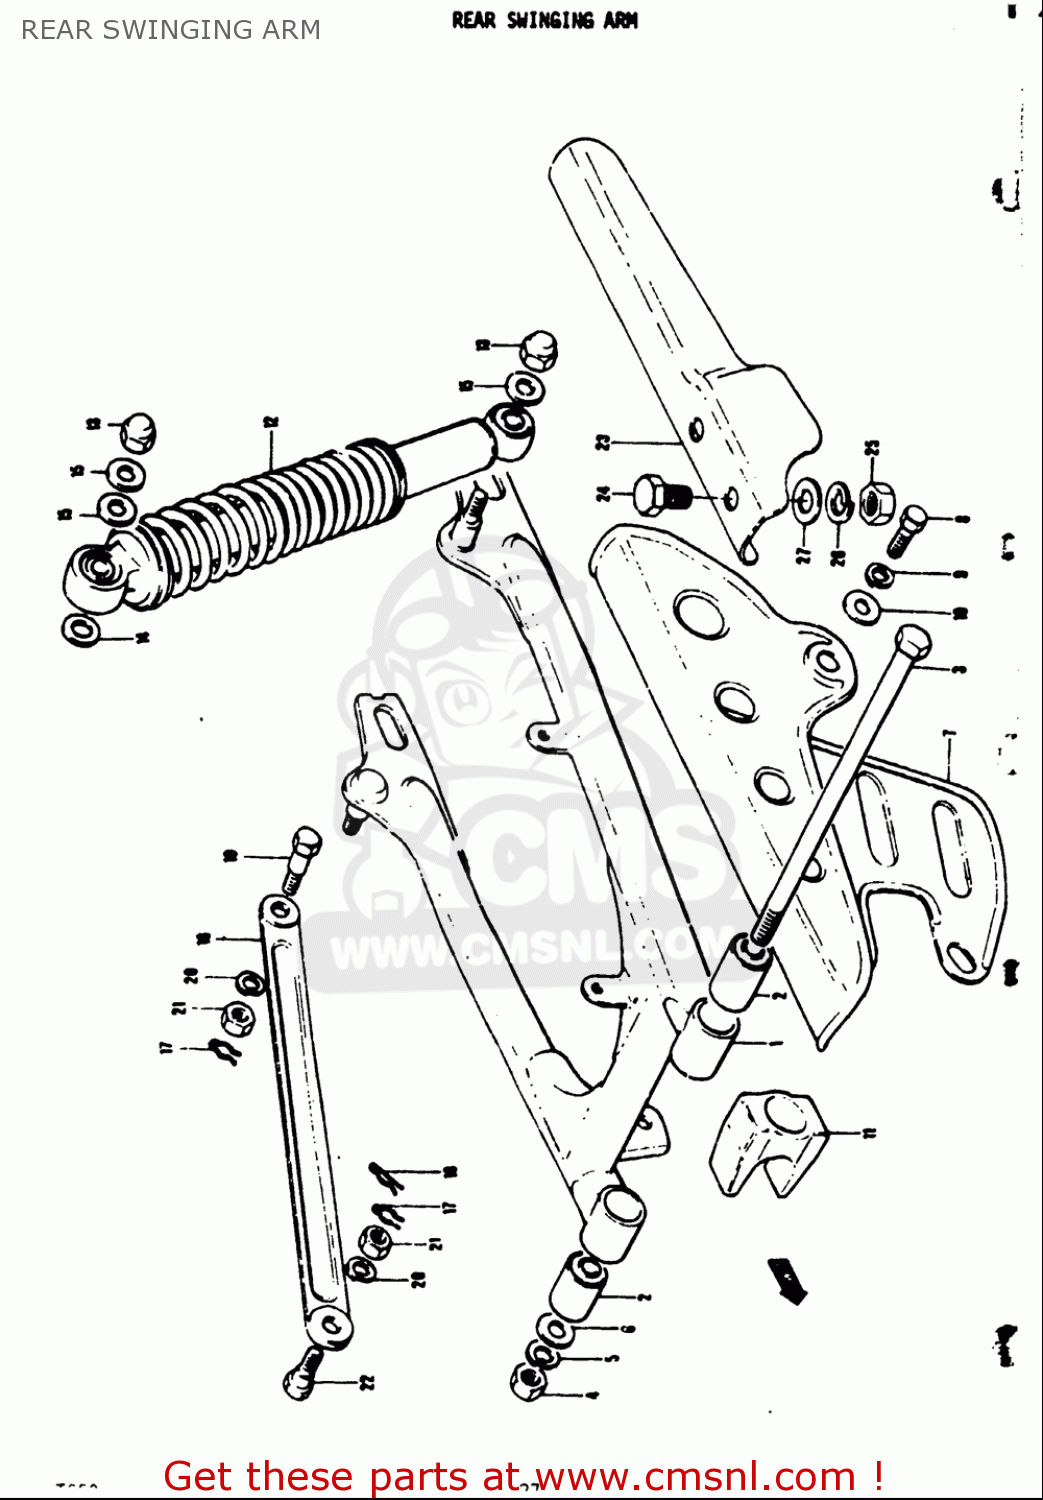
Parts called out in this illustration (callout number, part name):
2	BUSHING(10X23X35)
3	SHAFT,RR SHOCK ABSORBER UPR
4	NUT
5	WASHER,LOCK
6	WASHER
8	BOLT(6X8)
9	WASHER,LOCK
10	WASHER
12	ABSORBER ASSEMBLY,REAR SHOCK
13	NUT
14	WASHER
15	WASHER (10.5X24X2.3)
16	TORQUE LINK,REAR
17	RETAINER,SNAP
18	CLIP
19	BOLT(8X26.5)
20	WASHER,LOCK
21	NUT
22	BOLT(8X22.5)
24	BOLT
25	NUT
26	WASHER,LOCK
27	WASHER
